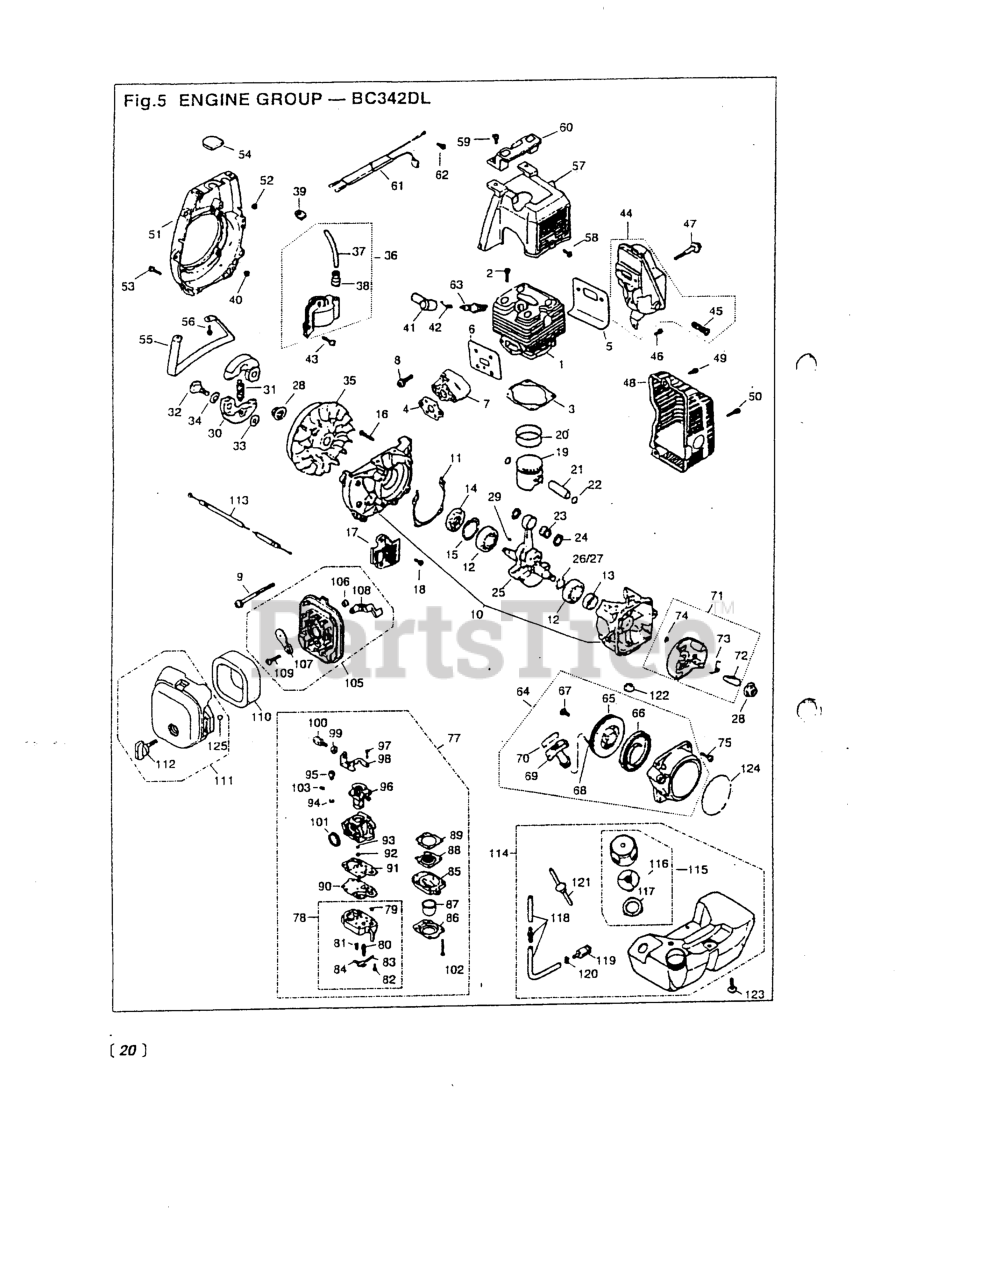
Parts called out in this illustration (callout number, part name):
1	CYLINDER (RPLS -12111)
2	BOLT M5 x 20 (RPLS -12280)
3	GASKET
8	SCREW, M5 x 25
9	SCREW, M5 X 55
10	CRANKCASE (RPLS -21101)
13	SEAL, OIL (RPLS 1100-21210)
14	SEAL, OIL (RPLS 1200-21220)
15	RING, SNAP, M32 x 1.2
16	BOLT, M5 X 30
17	GUARD (RPLS-21310)
18	SCREW,M5 X 14 (RPLS 1400-15510
20	RING, PISTON
21	PIN
22	RING, SNAP
23	BEARING
24	WASHER (RPLS 3310-41341)
25	CRANKSHAFT CO
26	SHIM (NO LONGER AVAILABLE)
29	KEY
31	SPRING, CLUTCH
32	SCREW
33	WASHER
36	COIL ASSEMBLY
39	GROMMET
42	SPRING
43	SCREW, M5X20 (RPLS.1400-75510)
44	MUFFLER ASSEMBLY
45	ARRESTER
46	SCREW, M5 X 12
48	COVER, MUFFLER
49	BOLT M5 x 20 (RPLS -12280)
50	BOLT
51	COVER, FAN
53	BOLT M5 x 20 (RPLS -12280)
56	BOLT (REPLACES 01252-30514)
57	COVER, CYLINDER (RPLS-32112)
58	SCREW, M5 X 12
59	SCREW, M5X20 (RPLS.1400-75510)
60	HEAD GUARD
61	CORD COMP
62	SCREW, M5 X 12
64	RECOIL ASSEMBLY
65	REEL
66	SPRING, SPIRAL
67	SCREW (RPLS -75150)
69	KNOB
71	PULLEY ASSEMBLY
72	RATCHET
73	SPRING, RETURN
74	E-RING
75	SCREW, M5X20 (RPLS.1400-75510)
77	CARBURETOR ASSEMBLY (WYJ-118)
78	BODY, PUMP
80	VALVE, INLET
81	SPRING, METERING LEVER
82	SCREW, METERING LEVER PIN
83	PIN, METERING LEVER
84	LEVER
85	BODY, PURGE
86	COVER, PUMP
87	PUMP, PRIMING
88	DIAPHRAGM (USE 4810-81260)
89	GASKET, DIAPHRAGM
90	DIAPHRAGM
91	GASKET, PUMP
92	JET
93	RING, O
94	RING
95	SWIVEL
96	VALVE ASSY
97	SCREW
99	NUT, CABLE ADJUSTER
101	RING, PACKING
102	SCREW
103	WASHER
105	LEVER, CHOKE
106	SLEEVE
107	PLATE, CHOKE (RPLS-82130)
108	LEVER, CHOKE
109	SCREW (REPLACES 50030272)
110	ELEMENT
113	CABLE COMP (RPLS 1633-83100)
116	VALVE COMPLETE
117	PACKING (RPLS -85321)
118	PIPE (RPLS 1601-85403)
119	FILTER ASSY
120	CLIP (REPLACES 2841-31280)
121	PIPE (RPLS 1601-85701)
122	WASHER
123	SCREW, M5 X 22
124	LABEL BC342DL (RPLCS. -75411)
125	RING
